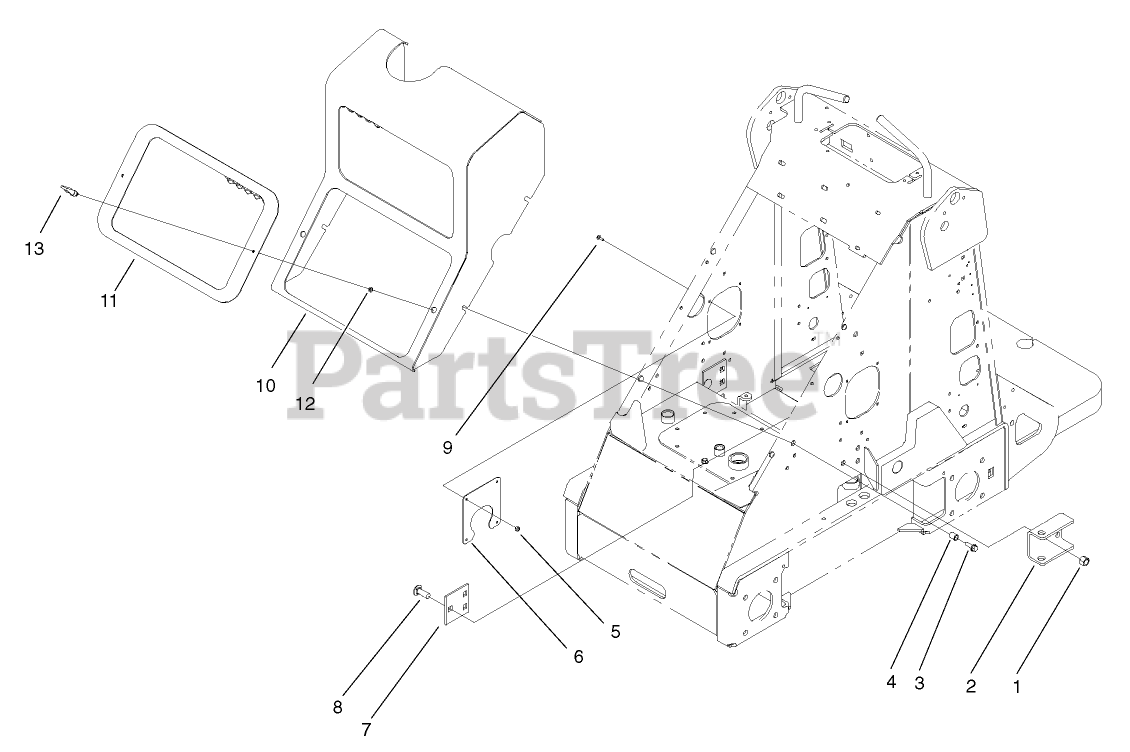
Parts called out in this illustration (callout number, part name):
1	NUT-LOCK, NI
2	BRACKET-ANCHOR
3	SCREW-HHF
4	INSERT-THREADED
5	NUT-LOCK, NI
6	GUARD-MUFFLER
7	PLATE-ANCHOR
8	SCREW-CARR, SHORT NECK
9	SCREW-CARR
12	WASHER
13	LATCH-SWELL
